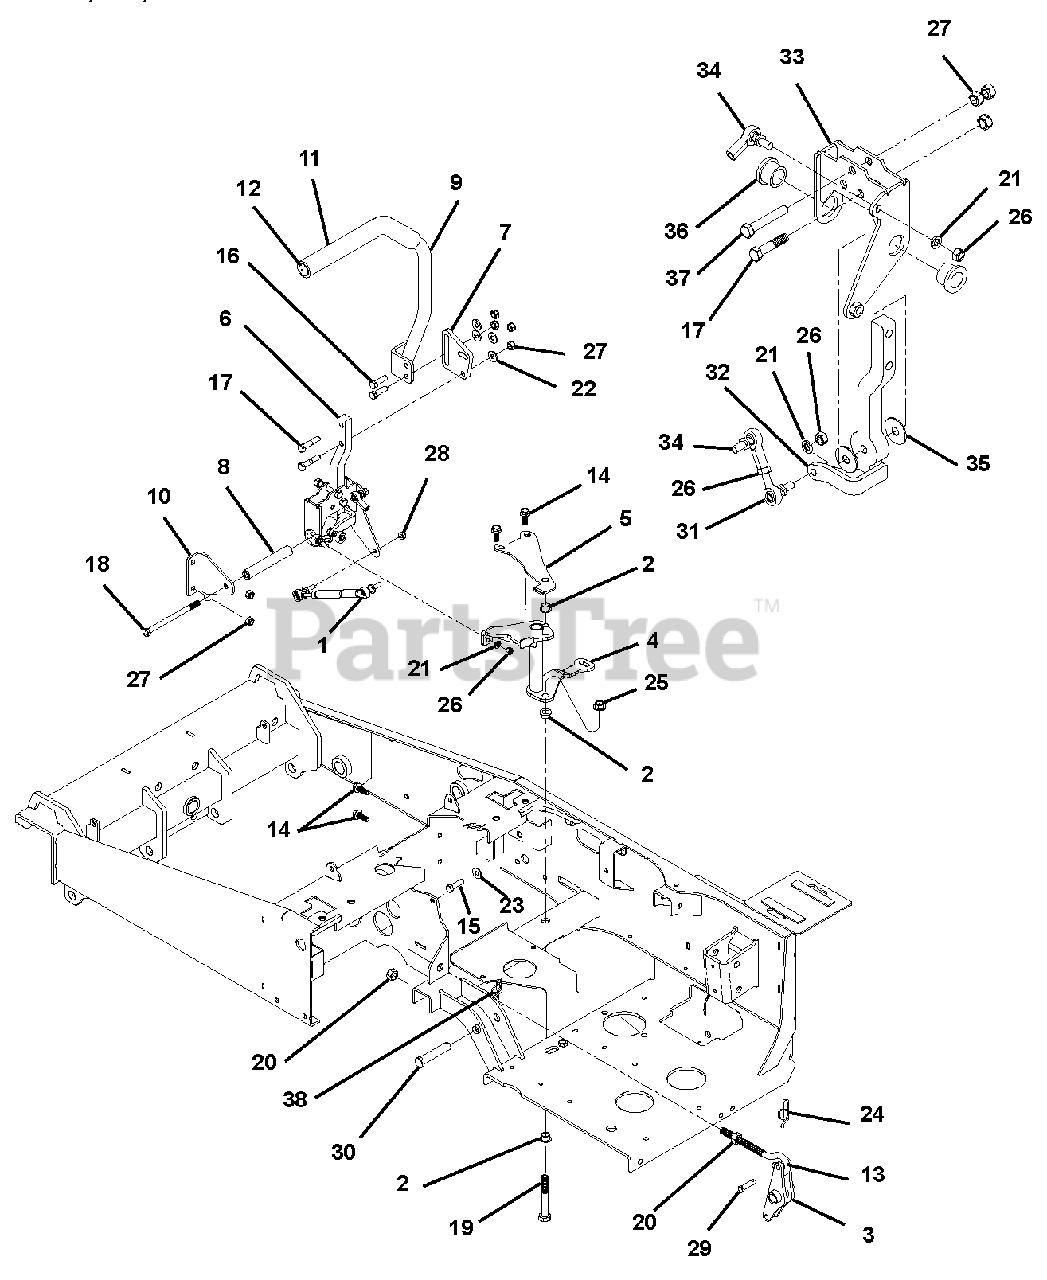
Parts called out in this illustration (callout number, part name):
1	Dampner, Steering Control
2	Bearing Shield 1/2"
3	Spring Pivot Weldment
4	Park Brake Control Arm RH
5	Ear, RH Brake Pivot
6	Handle Assembly RH
7	Handle Height Plate
8	Tube, Round .750 x .179 x 4.69
9	Weldment, RH Steering Handle
10	Plate, Bent
11	Grip, Foam (Serials 101 – 2499)
12	Plug, 7/8" End (Serials 101 – 2499)
13	Eyebolt, .5 x 6.9
14	Bolt, 3/8-16 x 1.00 FGH 8
15	Bolt, 3/8-16 x .750 Hex 5
16	Bolt, 3/8-16 x 1.25 Hex
17	Bolt, 3/8-16 x 1.75 Hex 5
18	Bolt, 3/8-16 x 5.50 Hex 5
19	Bolt 1/2-13 x 2.75
20	Nut, 1/2-13 STD Hex
21	Washer, Locking .31 x .078 Regular
22	Washer, Flat, Steel .38 x .875 x .083
23	Washer, Flat, Steel .438 x 1.00 x .083
24	Ring, Rue .375 x .054 x 1.254
25	Nut, Locking, Cone
26	Nut, 5/16-24 STD Hex
27	Nut, Locking, Flange .375-16
28	Nut, Locking Top M8-1.25 Crown
29	Pin, CVS .375 x 1.38 x 1.14
30	Pin, CVS .625 x 3.00 x 2.77
31	Ball Joint RH 5/16 Male W/ STD
32	Bar Weldment, RH Steering
33	Handle, Control Weldment, RH
34	Ball Joint, RH 5/16 Female W/STD
35	Nylon Washer, 1.27 OD x .400 ID
36	Bushing, .750 x 1.00 x .750
37	Bolt, 3/8-16 x 2.25 Hex 5
38	Ring, Rue .625 x .072 x 1.690
